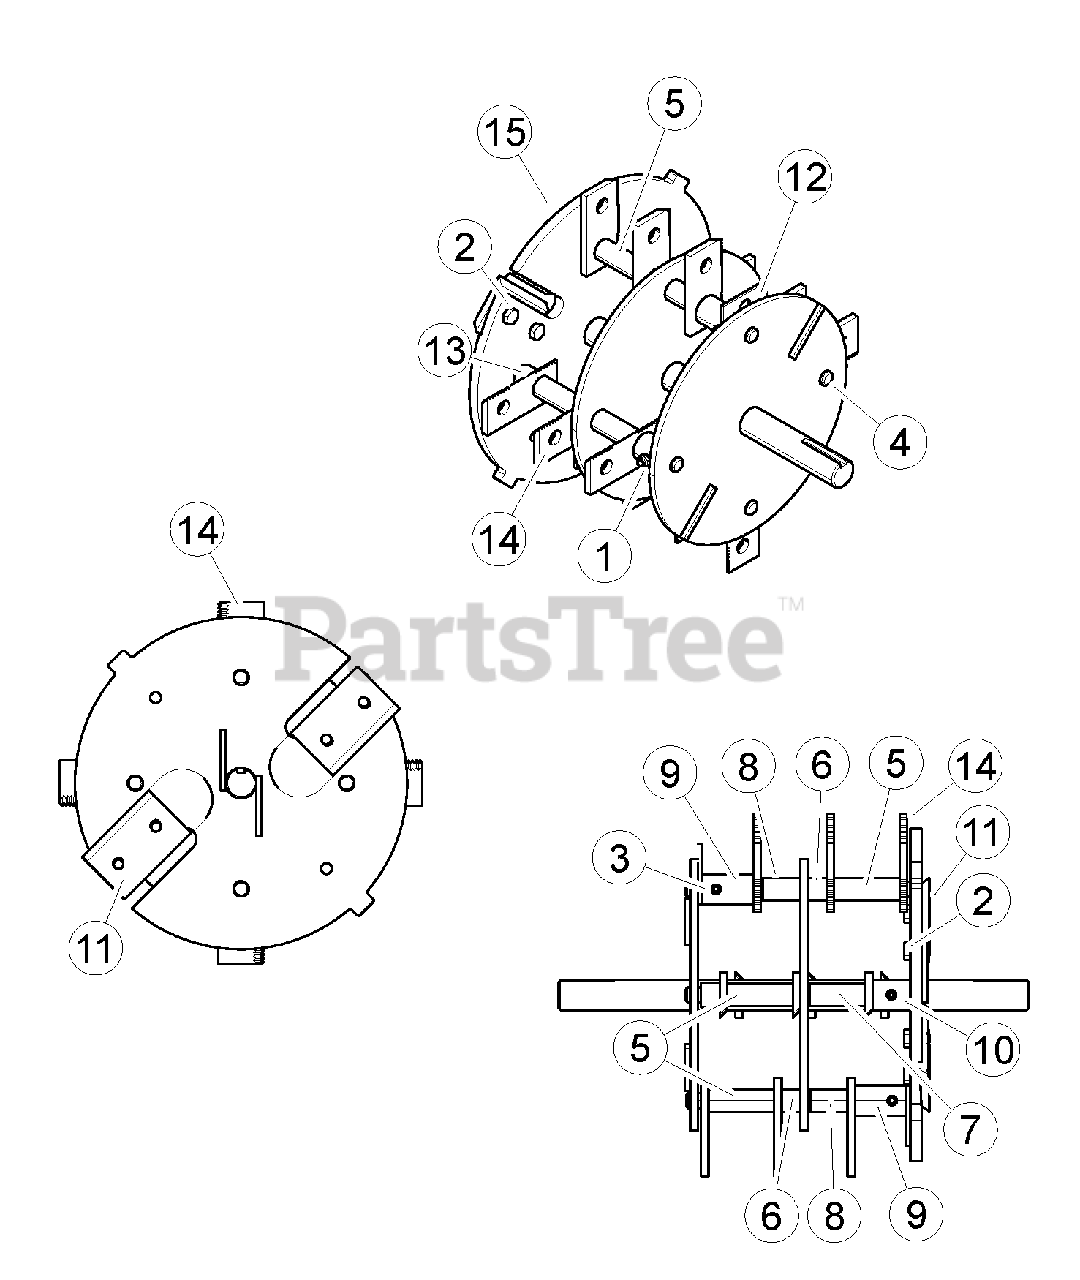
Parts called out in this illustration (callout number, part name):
1	NUT, 10/24 NYLOCK TYPE NM ZP
2	BOLT, 5/16-18 X 5/8" G8 HCS PATCH Z
3	SCREW, #10-24 X 1-3/8" PL SKT HD CAP
4	SPACER, 0.75 X 0.620
5	SPACER, 1.00 X 1.700 (W/ HOLE)
6	SPACER, 1.00 X 1.240 (W/ HOLE)
7	KIT, TOOL STEEL BLADE
8	KNIFE, ROTOR BALANCE
9	SPACER, 0.75 X 2.05
10	KIT, 3" NARROW SHREDDER KNIVES
11	WELDMENT, 3" NARROW ROTOR
12	SHAFT, KNIFE
